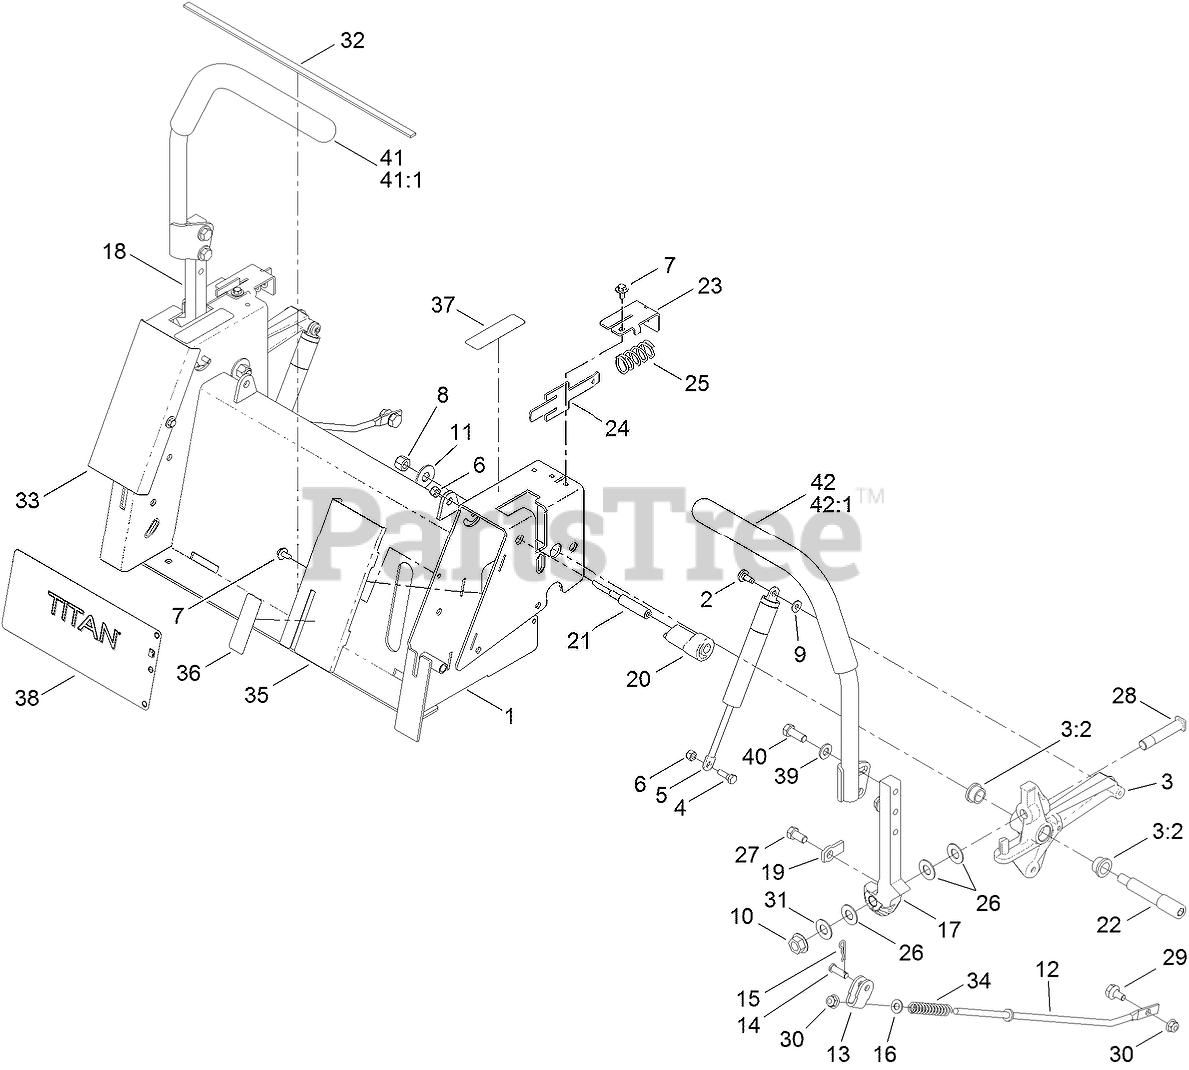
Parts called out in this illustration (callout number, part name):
1	BOX-CONTROL
2	SCREW-SHOULDER
3	ACTIVATOR ARM ASM
3:2	BUSHING
4	BOLT-SHOULDER
5	DAMPER-CONTROL, MOTION
6	NUT-LOCK, NI
7	SCREW-HHFTF
8	NUT-LOCK, NI
9	WASHER
10	NUT-HF
11	WASHER-FLAT
12	ROD-CONTROL
13	BRACKET-CONTROL
14	PIN-CLEVIS
15	PIN-COTTER
16	WASHER-PLAIN
17	ARM-ACTUATOR, LH
18	ARM-ACTUATOR, RH
19	TAB-STOP
20	ECCENTRIC
21	SCREW-ECCENTRIC
22	BOLT-SHOULDER
23	BRACKET-RETURN
24	PLATE-RETURN
25	SPRING-COMPRESSION
26	WASHER-PIVOT
27	SCREW-HH
28	BOLT-SHOULDER
29	BOLT-SHOULDER
30	NUT-HF, NI
31	WASHER-TEFLON
32	STRIP-VIBRATION, ANTI
33	COVER-CONTROL, RH
34	SPRING-RETURN, NEUTRAL
35	COVER-CONTROL, LH
36	DECAL-BRAKE, PARKING
37	DECAL-CONTROL, MOTION
39	WASHER-FLAT
40	SCREW-HH
41	RH LEVER/GRIP ASM
41:1	Grip-Control, Motion
42	LH LEVER/GRIP ASM
42:1	Grip-Control, Motion
